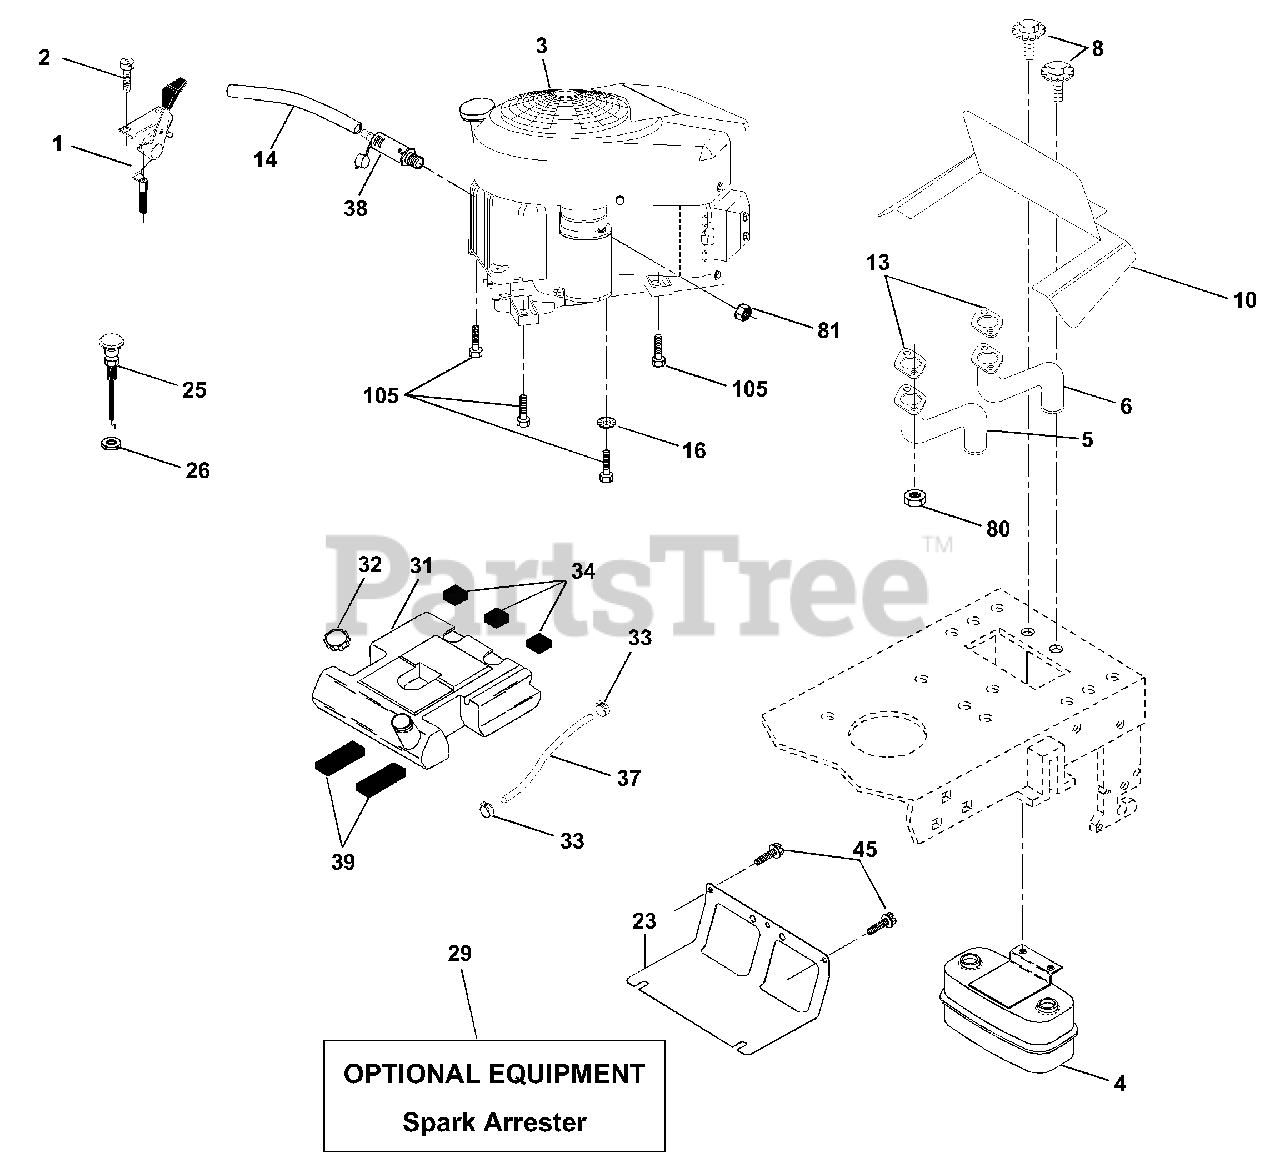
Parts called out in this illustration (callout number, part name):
1	Control Throt Flg
2	Screw Hex Thd Cut 1/4-20x5/8 T
4	Muffler Asm Twin Lo-Tone
5	Exhaust Tube
6	Exhaust Tube
8	Bolt 5/16-18unc x 3/4 W/Sems
10	Shield Browning
13	Gasket Muffler
14	Tube Drain Oil Easy
16	Washer Lock Ext Tooth 3/8
23	Shield Browning
25	Choke Control
26	Nut, Keps 3/8-24 Unf
29	Kit Spark Arrestor (Flat Scrn)
31	Tank Fuel 3 50 Rear
32	Cap Asm Fuel Top N/Lany Vented
33	Clamp Hose Blk
34	Pad, Spacer
37	Line Fuel
38	Plug Drain Oil Easy
39	Pad, Idler
45	Screw Hexwsh Thdr 3/8-16 x 3/4
80	Nut Flange M8-1.25
81	Nut Keps Hex 1/4-20 Unc
105	Screw 3/8-16 x 1
